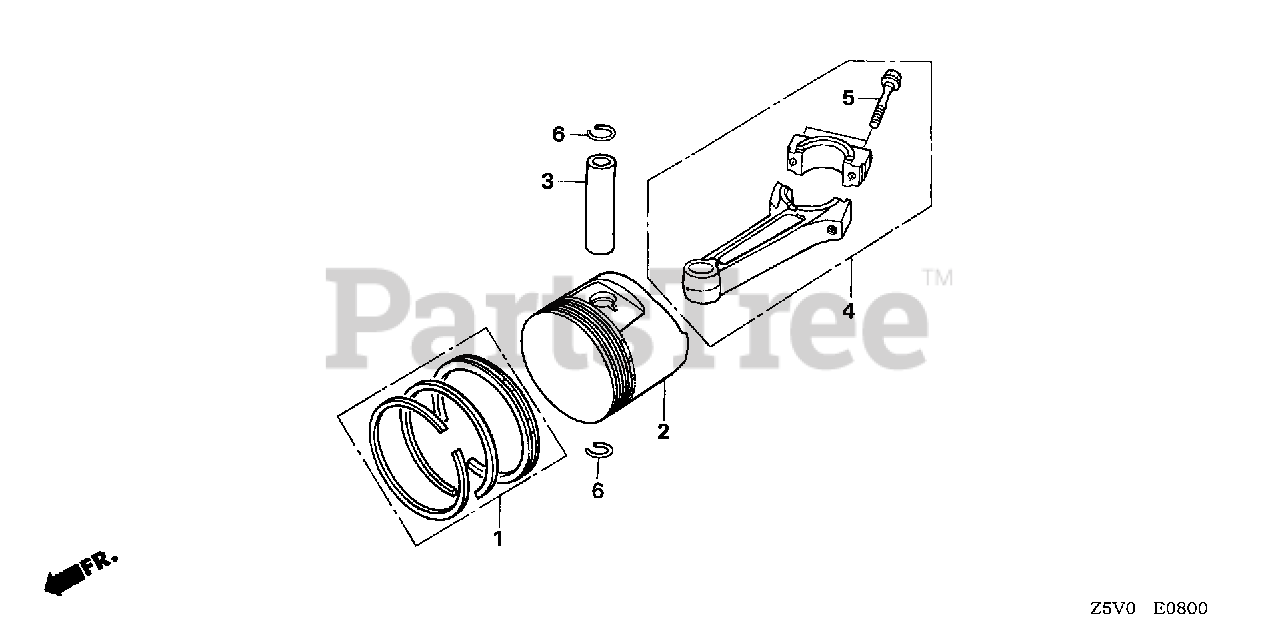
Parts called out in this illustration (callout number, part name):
1	RING SET, PISTON (STD) (TEIKOKU)
1	RING SET, PISTON (0.25) (TEIKOKU)
1	RING SET, PISTON (0.50) (TEIKOKU)
1	RING SET, PISTON (0.75) (TEIKOKU)
2	PISTON (STD)
2	PISTON (0.25)
2	PISTON (0.50)
2	PISTON (0.75)
3	PIN, PISTON
4	ROD ASSY., CONNECTING (STD)
4	ROD ASSY., CONNECTING (0.25 LOWER SIZE)
5	BOLT, CONNECTING ROD
6	CLIP, PISTON PIN (20MM)
